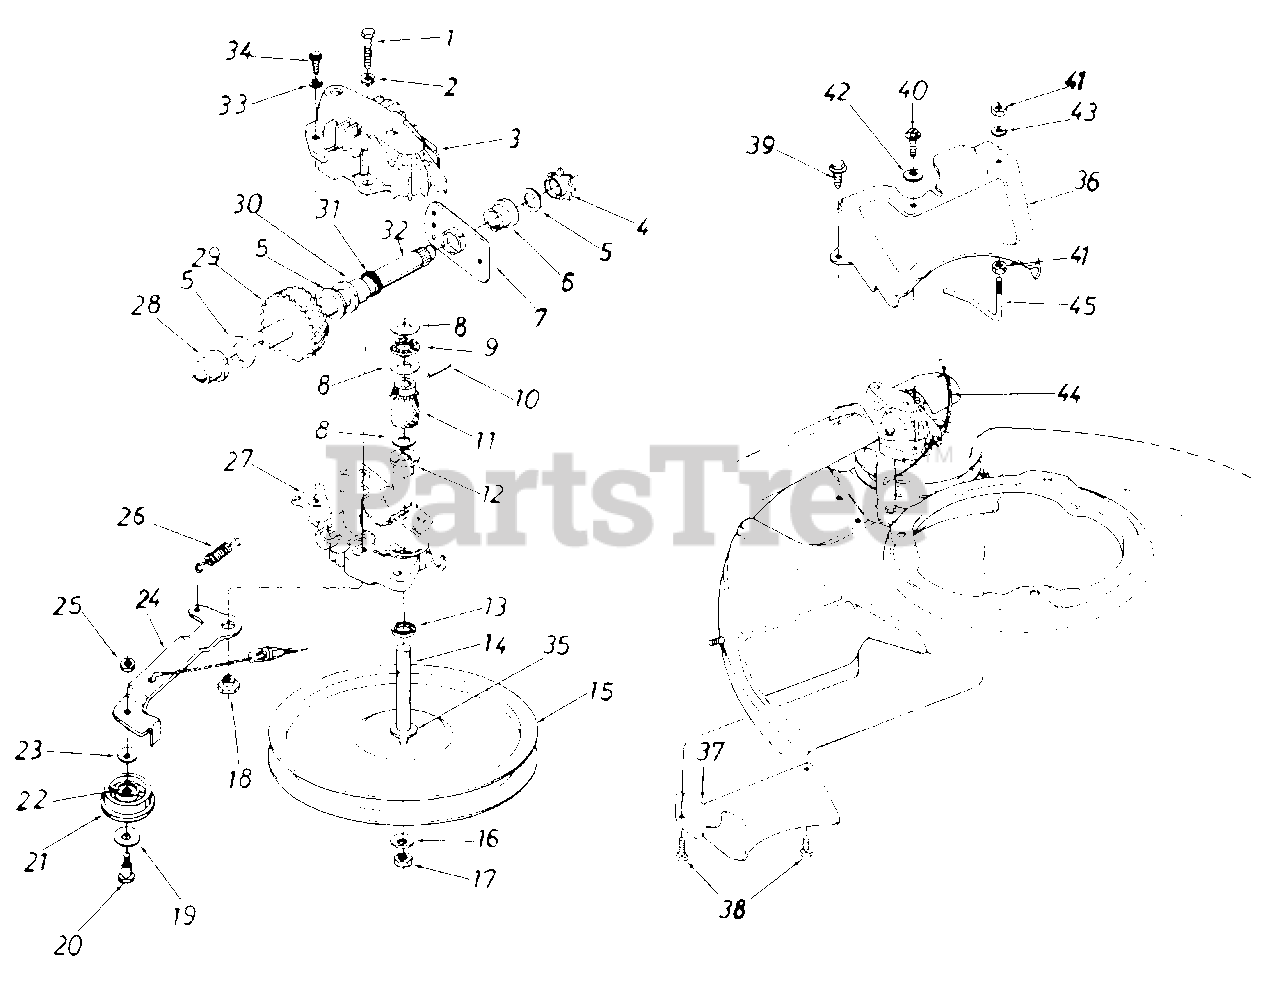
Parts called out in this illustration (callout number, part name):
1	Hex Bolt 1/4-20 x 1.25" Lg.
2	L-Wash. 1/4" I.D.
3	Upper Hsg. Half
4	#48 Sprocket 7 Tooth x 1/2 Pitch
5	Fl-Wash. 5/8" I.D. x .030
6	Hex Flange Brg. .631" I.D.
7	Hex Bearing Cup
8	Thrust Wash. .382" I.D. x .70" O.D.
9	Thrust Bearing .375" I.D. x .812" O.D.
10	Spring Pin Spir. 1/8" x .62" Heavy
11	11 Tooth Helical Gear
12	Flange Bearing
14	Pulley-Transmission Shaft
15	Fl-Pulley 5.06" O.D.
16	Bell-Wash. .265" I.D. x .75"
17	Hex L-Nut 1/4-28 Thd.
18	Shld. Spacer .375" Dia. x .170
19	Fl-Wash. .390" I.D. x 1.0"
20	Shld. Bolt .375" Dia. x .40"
21	Fl-ldler Plastic 1.50" Dia.
22	Needle Brg. .375" x .31
23	Bell-Wash. .265" I.D. x 75"
24	Idler Brk t. Ass'y
25	Hex Patch L-Nut 1/4-28 Thd.
26	Extension Spring 1.12" Lg.
27	Lower Hsg. Half
28	Flange Bearing .566 Dia.
29	33 Tooth Helical Gear
30	Flange Bearing .629 Dia.
31	Oil Seal .625 Dia.
32	Gear Sprocket Shaft
33	L-Wash. #10 I.D.
34	Hex B-Tap Scr. #10 x .62"
35	Hex Washer .26" x .88"
36	Transmission Belt Guard
37	Belt Cover
38	Hex B-Tap Scr. 1/4 x .38" Lg.
39	Hex AB-Tap Scr. 1/4 x .50" Lg.t
40	Hex B-Tap Scr. 1/4 x .62" Lg.
41	Hex Nut 1/4-20 Thd.
42	Bell-Wash. .265" I.D. x .75"
43	L-Wash. 1/4" kD.
44	S.P. Cable-50" Lg.
45	S.P. Belt Guard
